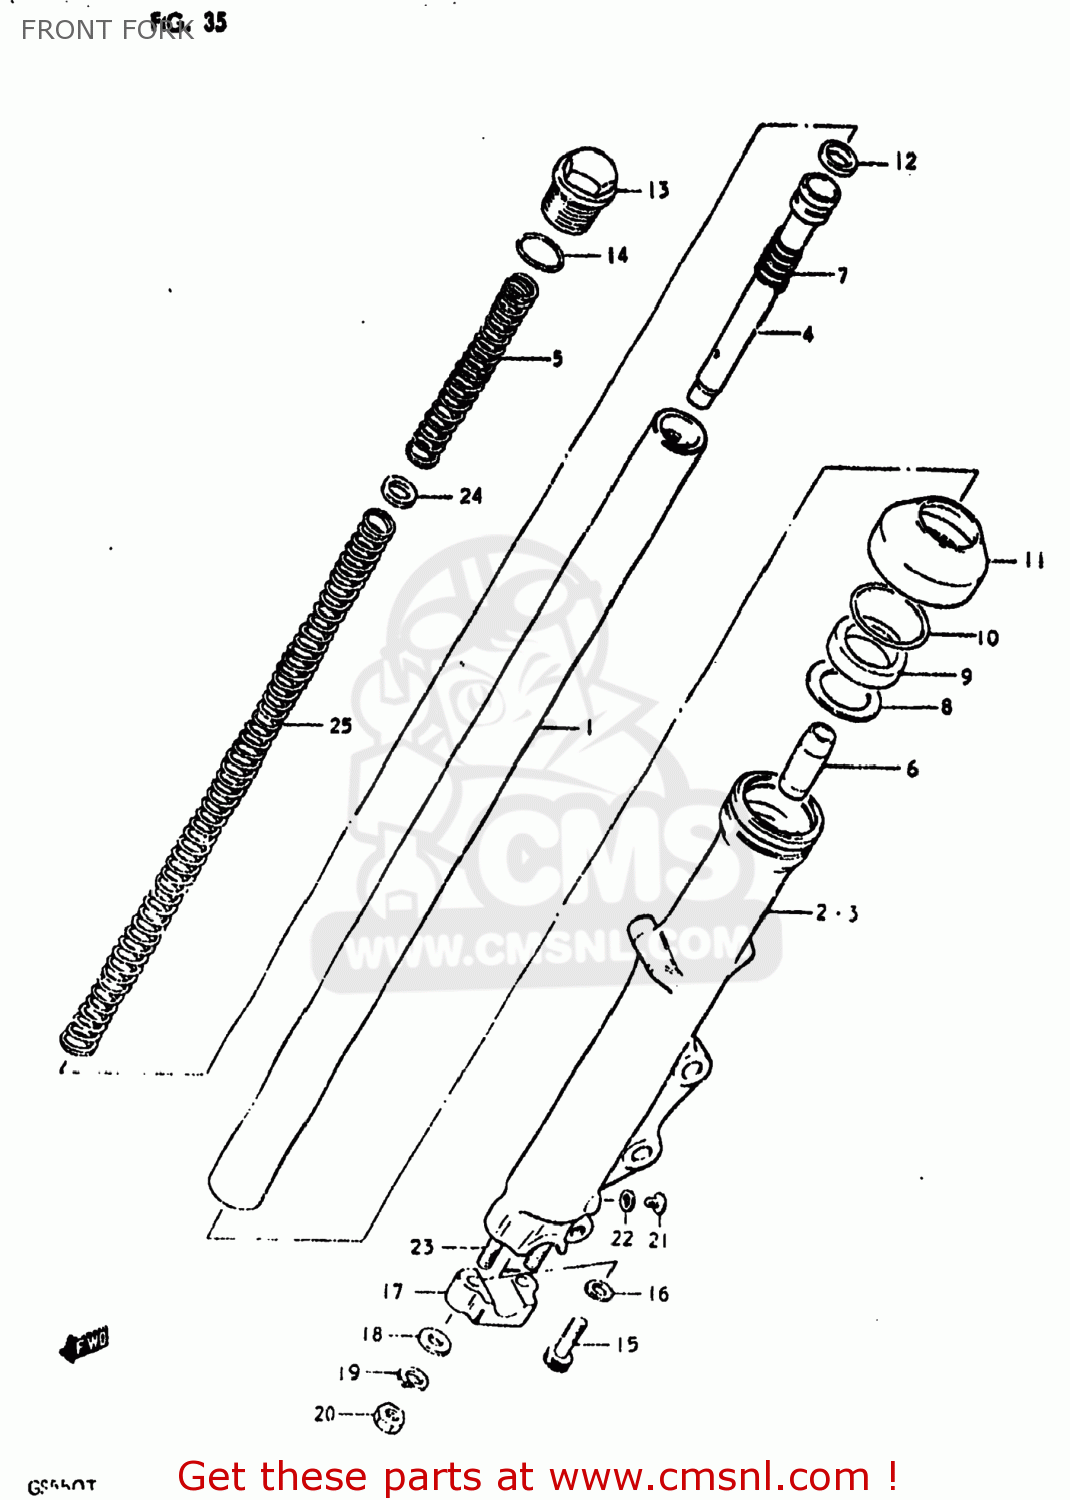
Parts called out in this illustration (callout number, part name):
0	DAMPER ASSEMBLY,LEFT
1	TUBE,FORK,INNER
2	TUBE,FORK,OUTER,RIGHT
3	TUBE,FORK,LEFT,OUTER
4	SEAT,FRONT FORK,UNDER
5	SPRING
6	PIECE,OIL LOCK
7	SPRING,FORK REBOUND
8	SPACER,SEAL
9	OIL SEAL,FRONT FORK
10	CIRCLIP,FORK OIL SEAL
11	BOOT
12	RING
13	CAP,INNER TUBE
14	O RING
15	BOLT(8X27)
16	GASKET (NAS)
17	HOLDER,AXLE
18	WASHER
19	LOCK WASHER
20	NUT
21	SCREW 4X6
22	GASKET (NAS)
23	STUD 8X25
24	WASHER
25	SPRING,FRONT FORK
